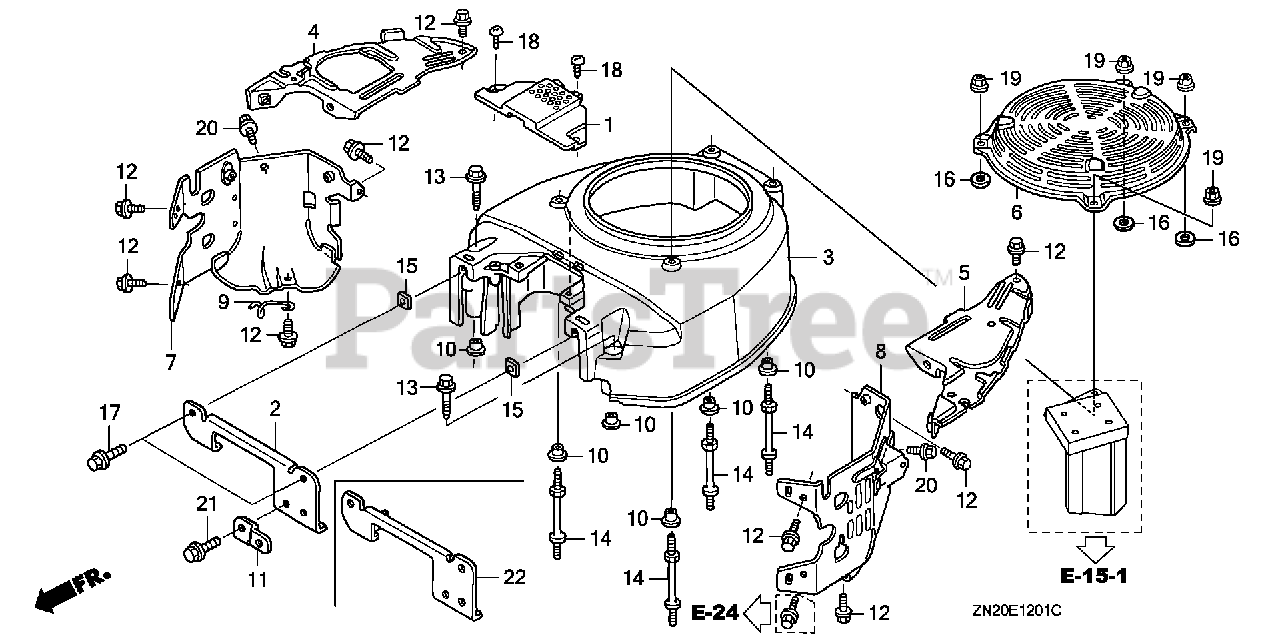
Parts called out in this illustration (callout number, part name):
1	COVER, FUEL PUMP
2	COVER, FUEL PUMP
3	COVER, FAN *R280* (RECOIL STARTER) (POWER RED)
4	PLATE, SIDE
5	PLATE, SIDE
6	PROTECTOR, FAN COVER *R280* (POWER RED)
9	CLAMP, IGNITION TUBE
10	COLLAR B, TAILLIGHT
11	BASE, CLIP
12	BOLT, FLANGE (6X12) (CT200)
13	BOLT, FLANGE (6X23) (CT200)
14	BOLT, STUD (6X71)
15	NUT, SQUARE (5MM)
16	WASHER, CRANK ARM
17	SCREW-WASHER (5X12)
18	SCREW, TAPPING (5X20)
19	NUT, FLANGE (6MM)
20	BOLT, FLANGE (6X8)
21	BOLT, FLANGE (6X12)
